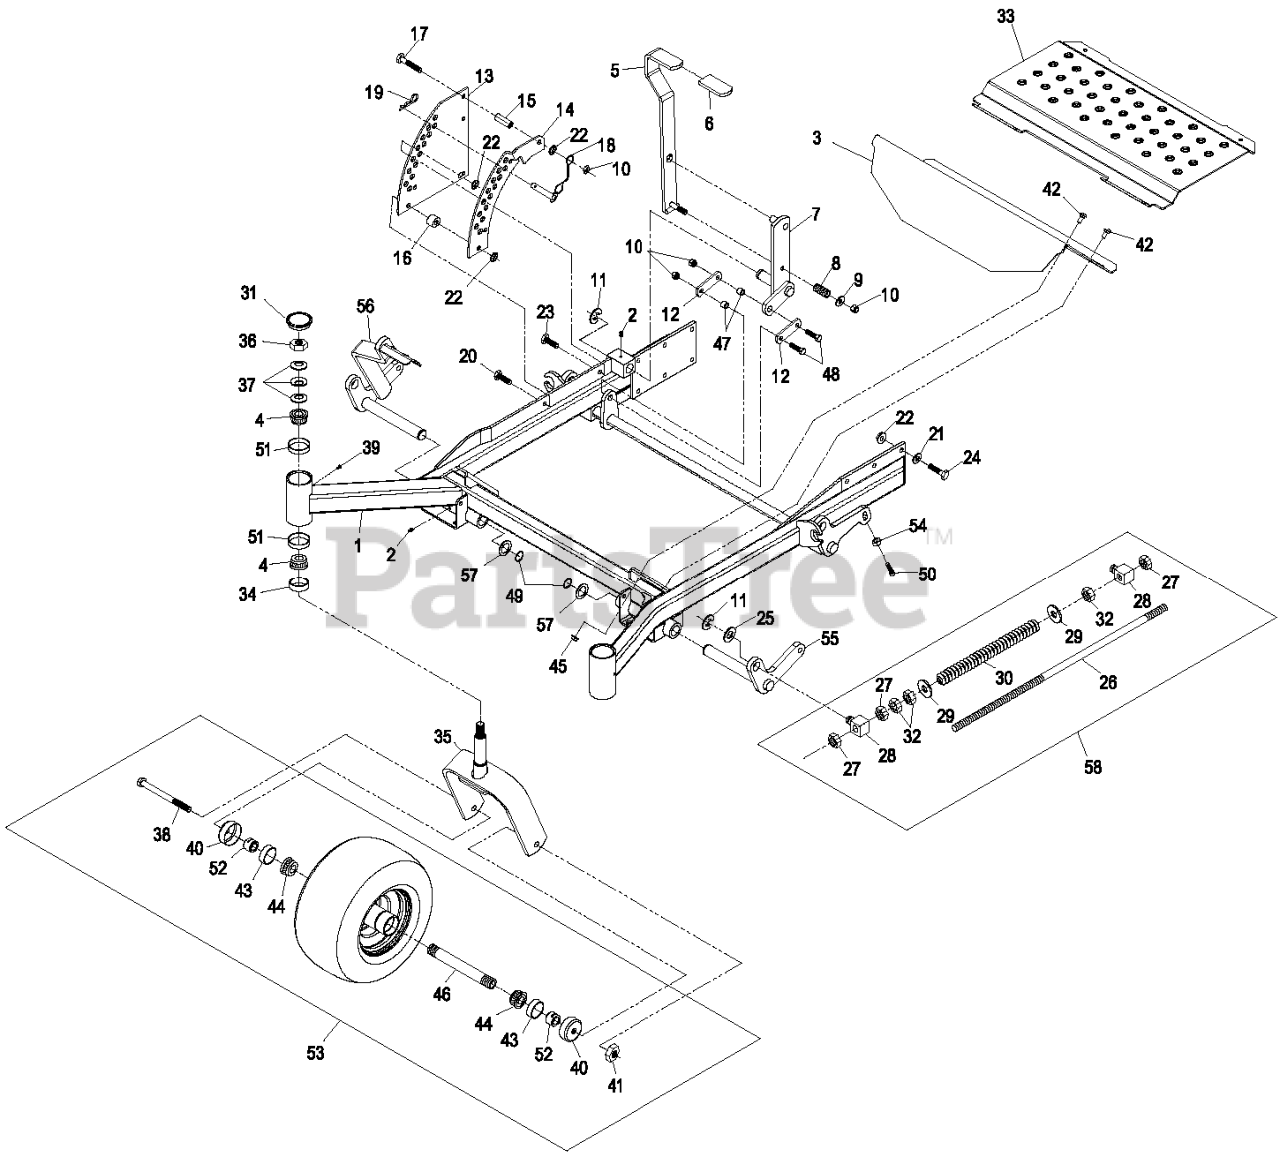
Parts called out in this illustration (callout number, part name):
1	ASM, FRONT FRAME 60"
2	FITTING-GREASE
3	ASM, FLOORPAN FRONT W/DEC
4	Cone-Bearing Tapered Roller
5	LIFT LEVER/GRIP ASM
6	GRIP-LEVER, LIFT
8	SPRING-COMPRESSION
9	WASHER-FLAT
10	NUT-LOCK, NI
11	RING-RETAINING, EXT
12	ARM-LIFT, DECK
13	PLATE-LIFT, DECK
14	PLATE-LIFT,DECK W/DECAL L
15	BUSHING-LEVER, LIFT
16	Stop, Deck Height
17	SCREW-HH
18	PIN-HITCH (W/LANYARD)
19	PIN-COTTER
20	SCREW-HH
21	WASHER-BELLEVILLE
22	NUT-HHF, WHIZ
23	SCREW-HH
24	SCREW-HH
25	WASHER-FLAT
26	ROD-LIFT, DECK
27	NUT-HEX
28	SWIVEL-DECK MOUNT, REAR
29	WASHER-FLAT
30	SPRING,DECK SUPPORT
31	CAP-GREASE
32	NUT-JAM
33	ASM, FLOORPAN LIFTOUT W/D
34	SEAL-GREASE
36	NUT-LOCK, NI
37	WASHER-BELLVILLE
38	SCREW-HH
40	GUARD-SEAL
41	NUT-LOCK, NI
42	BOLT-CARR
43	SEAL-CASTER
44	BEARING-CONE, TAPERED ROLLER
47	BUSHING
48	SCREW-HH
49	RING-RETAINING
50	SCREW-HSH
51	CUP-BEARING
52	SPACER-NUT
53	WHEEL & TIRE ASM
54	NUT-JAM
55	WLD,FRONT LIFT SHAFT-LH
56	WLD,FRONT LIFT W/LEVER
57	WASHER-SPACER
58	ASM,FRONT FRAME SPRING
